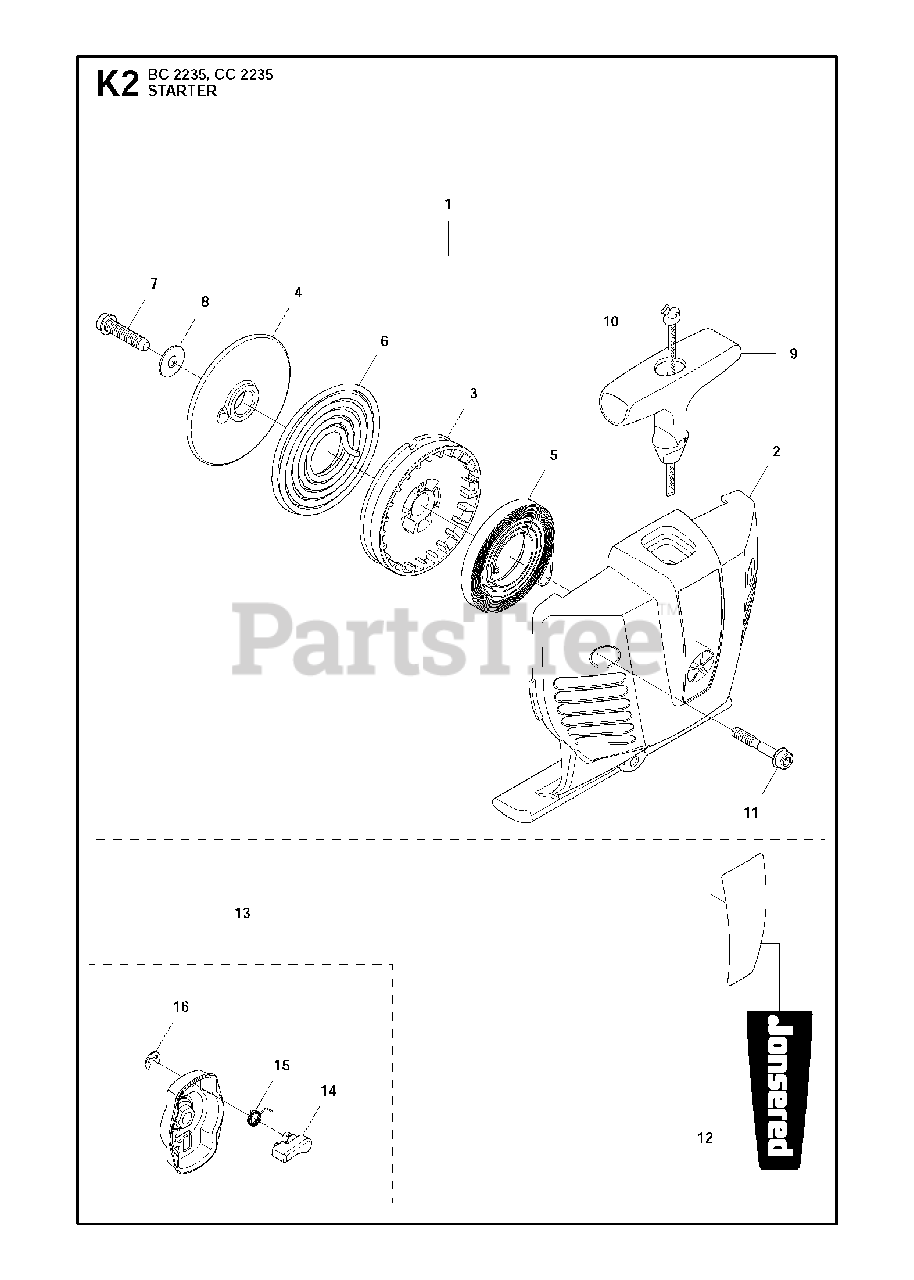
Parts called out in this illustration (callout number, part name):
5	STARTER SPRING
7	%SCREW
9	HANDLE
10	STARTER ROPE
11	SCREW
13	STARTER PAWL BRIDGE
14	STARTER PAWL
15	SPRING
16	E-RING 4
